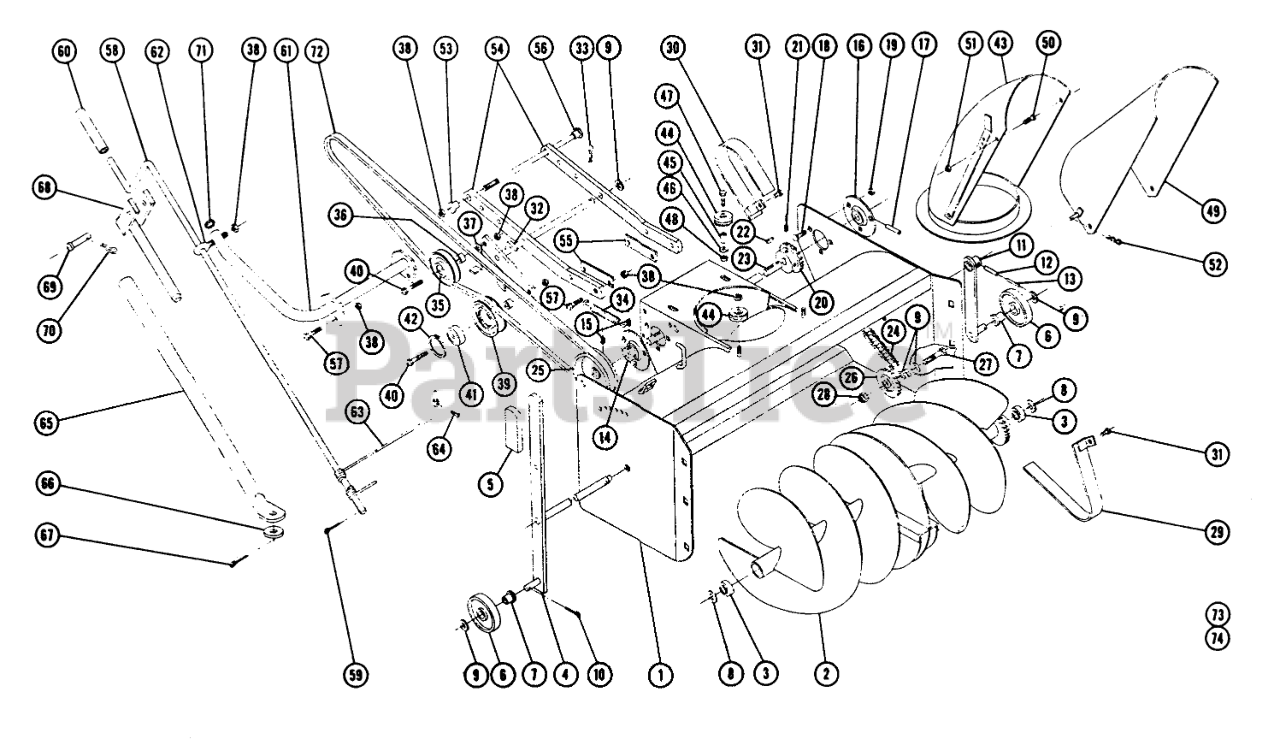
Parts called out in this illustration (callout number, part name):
1	Ass-y. Wrapper
2	Auger
3	Bearing
4	ASSY AUGER SHAFT R
5	GRIP
6	Wheel
7	Bushing
8	Washer Auger
9	Washer
10	Cotter Pin
11	Wheel Support
12	ROLL PIN 1/4 X 1-1/4
13	Roll Pin 5/32 x 1/4
14	Bearing-Flanged
15	Set Screw 5/16-18 x 5/16
16	Bearing Flanged
17	PIN-ROLL, SPIROL
18	Bolt Hex 5/16-18 x 3/4
19	Nut-Nylok
20	SPROCKET
21	Set Screw 1/4-20 x 1/4
22	Key
23	Shaft-Drive
24	Chain
25	Pulley-Drive Shaft
26	Idler Sprocket
27	Bolt-1/2-13-1 3/4
28	Nut-ES 1/2-13
29	Ass-y Guard-Inner
30	Guard-Outer
31	SCREW
32	Ass-y. Idler Arm
33	Hairpin
34	Spring
35	Pulley
36	Spacer
37	Clip - Belt
38	3/8-16 E.S.
39	Pulley Idler
40	Bolt Hex 3/8-16
41	BEARING
42	Snap Ring 1 3/8 Bore
43	S/A SHROUD R
44	Roller
45	SPACER
46	Washer
47	Bolt 1/4 20 x 1 1/4
48	Nut-Nylok
49	Deflector
50	Bolt Rd. Hd. 1/4-20 x 1/2
51	Nut, 1/4-20
52	Hairpin
53	Spacer
54	Arm Mounting
55	Shim
56	Ass-y. Rod & Spacer
57	Bolt 3/8-16 x 1
58	Crank
59	Cotter Pin
60	Tube
61	Ass-y. Control Support
62	Eye Bolt
63	Cable
64	Screw-Rd. Hd. Mach. #6-32 x 1/4
65	Ass-y. Tube & Bar
66	Washer, 5/8
67	Cotter Pin 3/16 x 1
68	Ass-y. Lift Rod
70	Hair Pin
71	Plug-Button
72	"V" Belt
73	Decal-Caution
74	Decal
